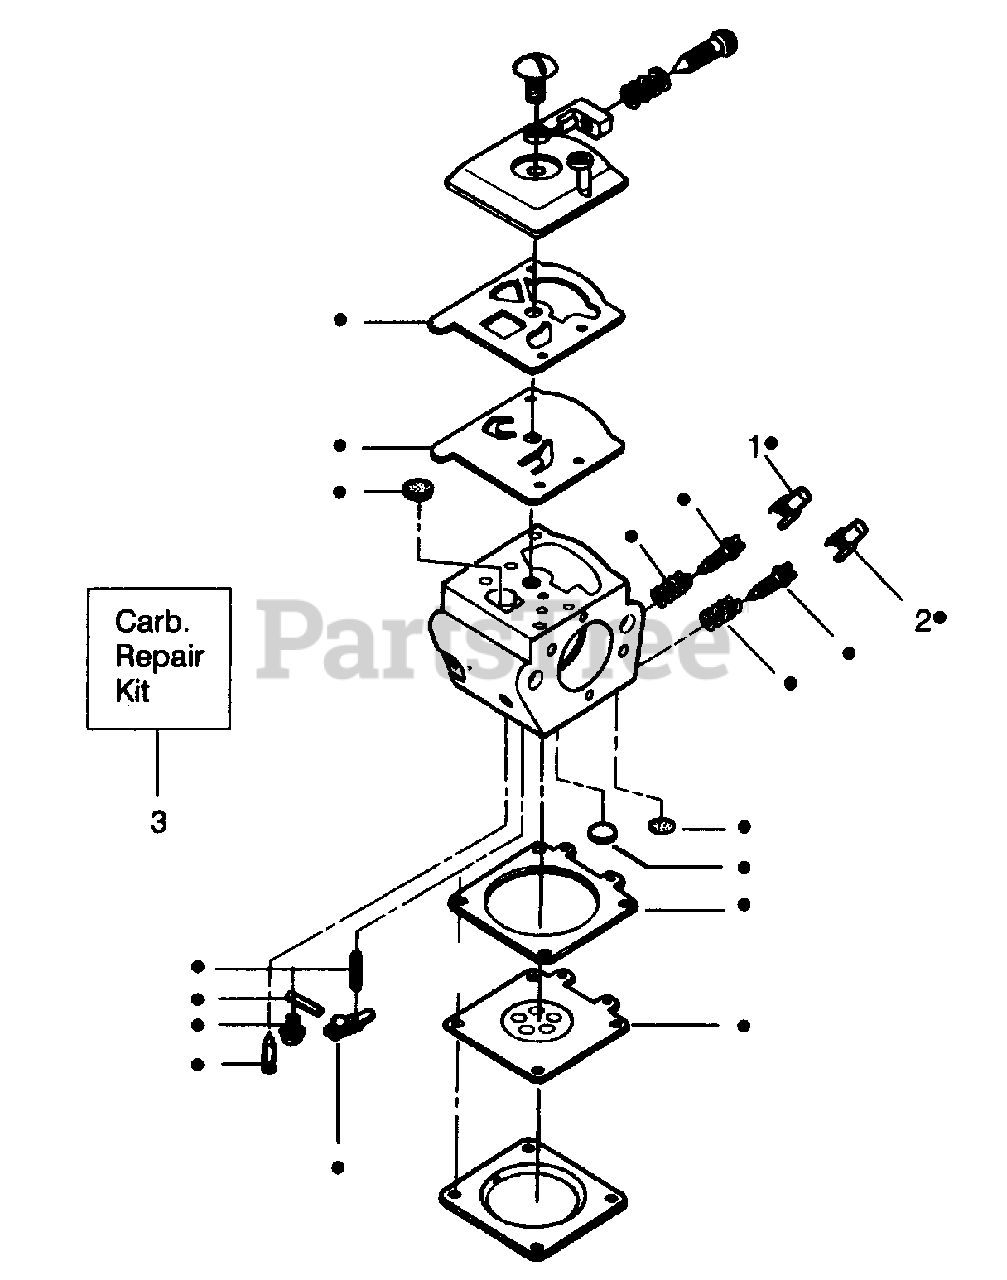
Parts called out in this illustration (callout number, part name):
1	Limiter Cap-High
2	Limiter Cap-Low
3	Carburetor Repair Kit (ù Indicates Contents)
